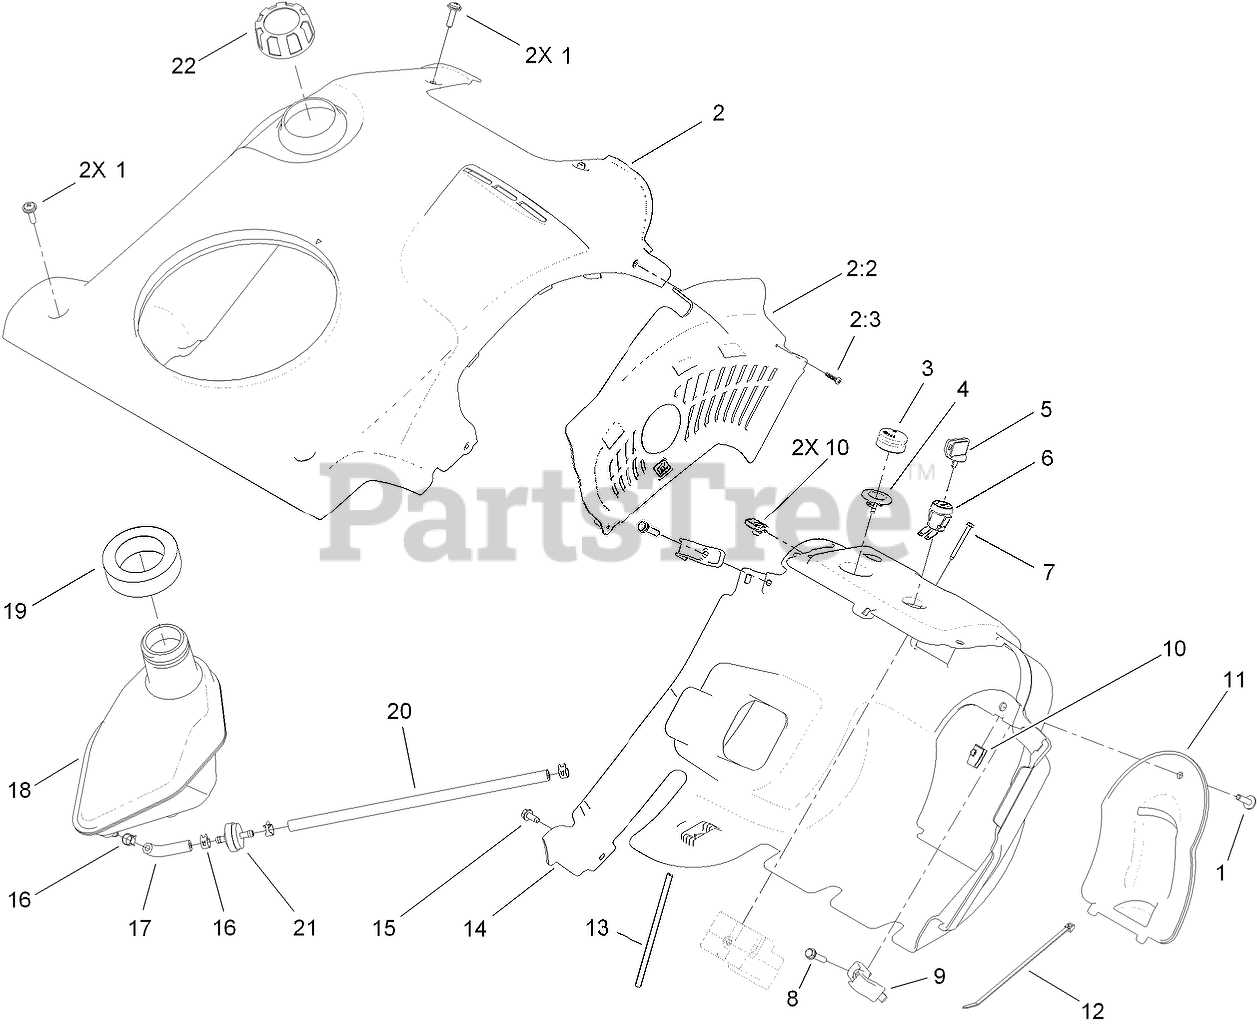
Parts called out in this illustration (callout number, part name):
1	SCREW-PPH
2	SHROUD ASM
2:2	BAFFLE-HEAT
2:3	SCREW-PPH
3	BULB-PRIMER
4	BODY-PRIMER
5	KEY-IGNITION
6	SWITCH
7	SCREW-PLASTITE
8	SCREW-PLASTITE
9	CLIP-SHROUD
11	PANEL-ACCESS, CARBURETOR
12	TIE-CABLE
13	HOSE-PRIMER
14	SHROUD-LOWER
15	SCREW-HWH
16	CLAMP-HOSE
17	HOSE-FUEL
18	TANK-GAS
19	SEAL-TANK
20	HOSE-FUEL
21	FILTER-FUEL
22	GAS CAP ASM
